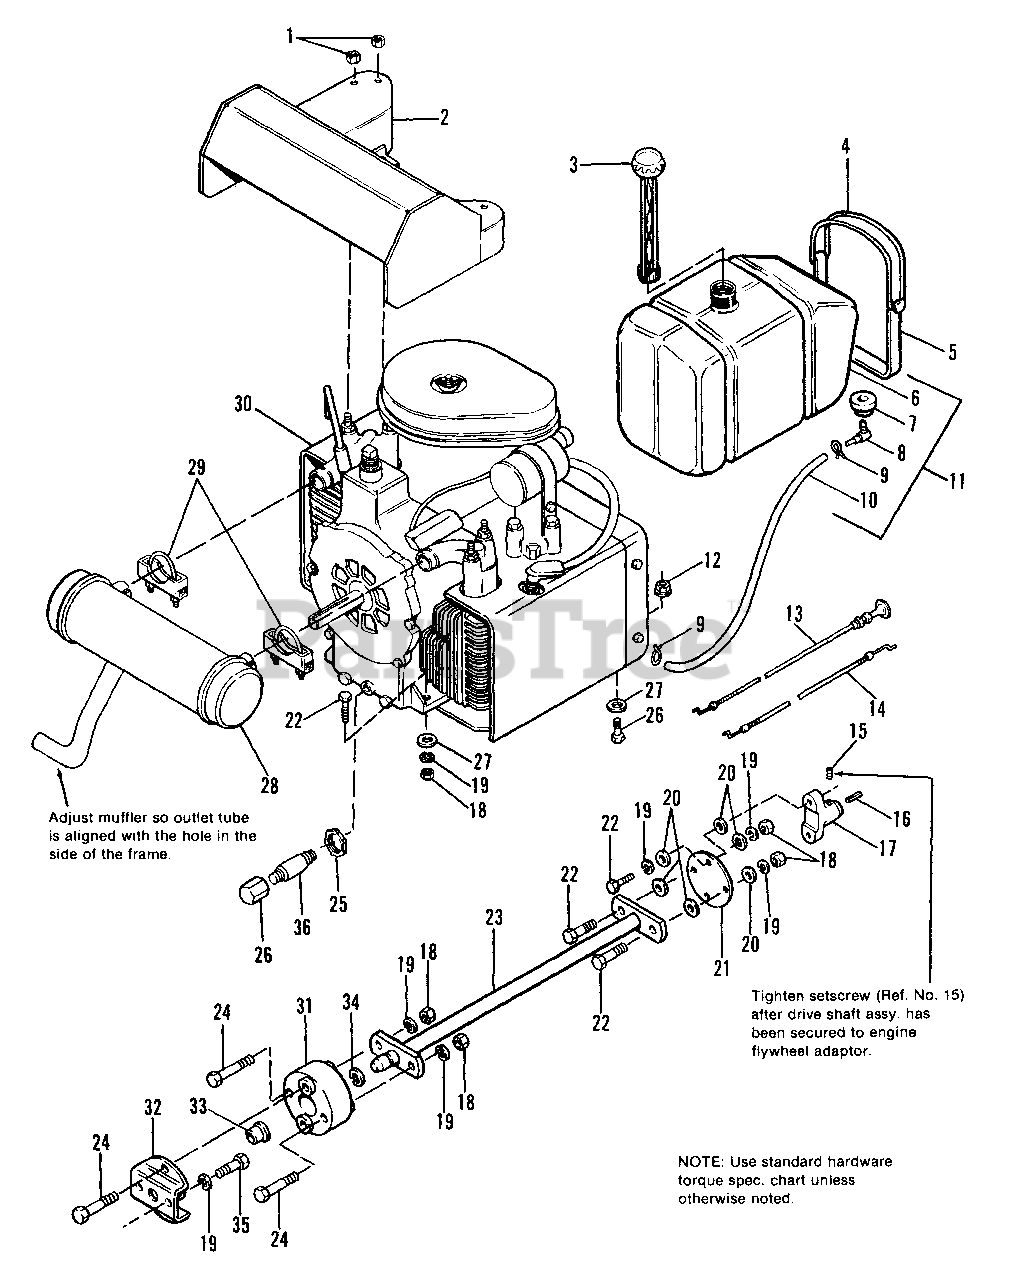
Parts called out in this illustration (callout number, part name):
1	LOCKNUT, Hex, Flange, 3/8-18
2	SHIELD ASSY., Heat
3	CAP, Fuel Tank
4	STRAP, Fuel Tank
5	STRAP, Tank
9	CLAMP, Hose
11	TANK ASSY., Fuel
12	LOCKNUT, Hex, Flange, Whiz, 3/8-16
13	CONTROL, Choke
14	CONTROL, Throttle
15	SETSCREW, 3/8-24 x 3/8
17	FLANGE, Drive Shaft
18	NUT, Hex, Full, 3/8-16
19	LOCKWASHER, 3/8
20	WASHER, Special
22	CAPSCREW, Hex Hd., 3/8-16 x 1-1/4
23	SHAFT ASSY., Drive
24	CAPSCREW, Hex Hd., 3/8-16 x 2-1/2
25	LOCKNUT, 3/8-18
26	CAP, Pipe, Hex
27	WASHER, Plain, 3/8
28	MUFFLER, Exhaust
29	CLAMP, Exhaust
30	ENGINE, 17 HP Kohler
31	COUPLING, Compression
32	PLATE ASSY., Adaptor
33	BUSHING (17 HP only)
34	RING, Retaining (17 HP only)
35	CAPSCREW, Hex Hd., 3/8-16 x 7/8
36	NIPPLE, Pipe, 3/8
